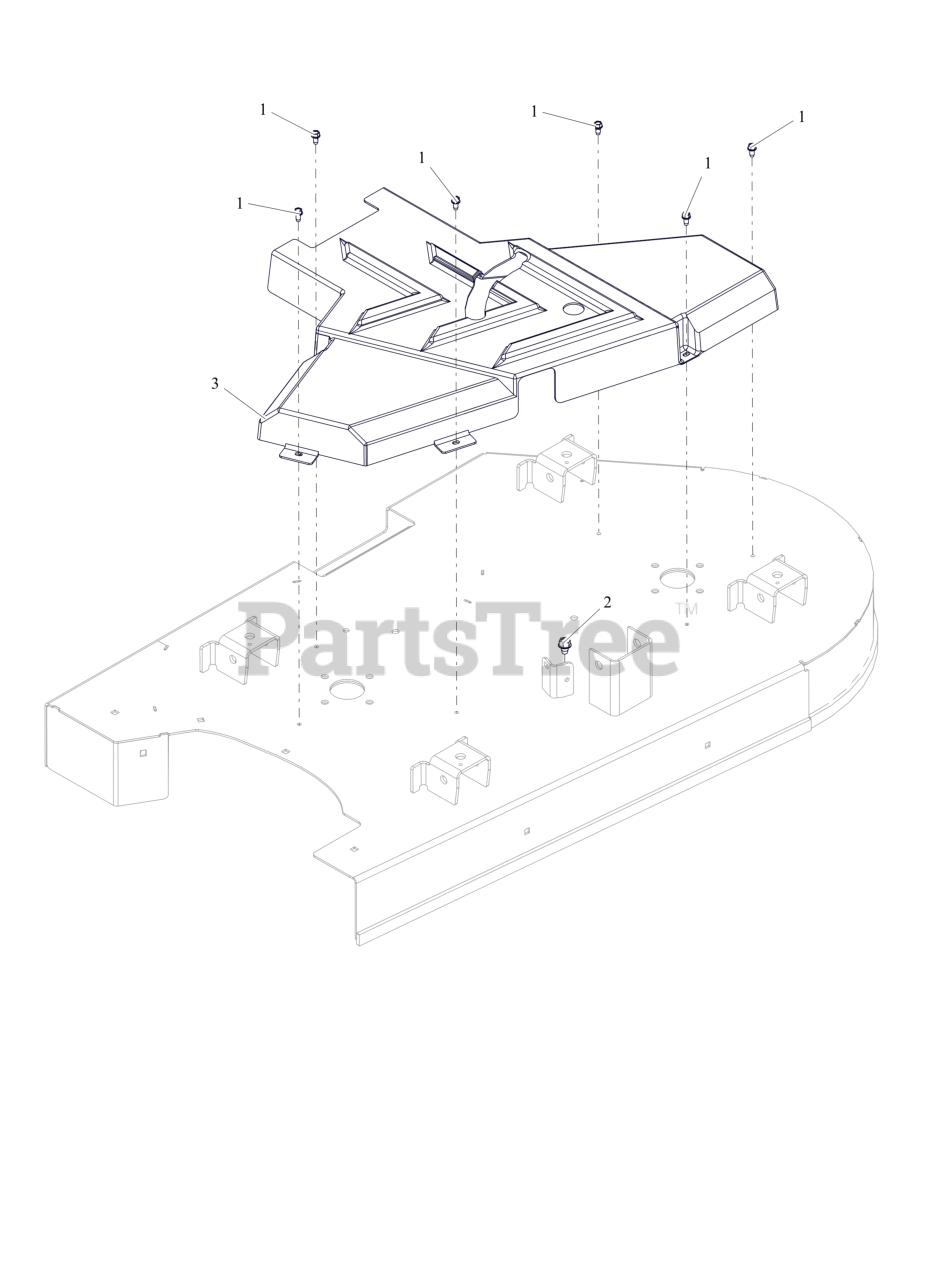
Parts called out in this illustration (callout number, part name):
1	SCR-TAP .25-20X.50 HWH ZCC
2	SCR,TAP .375-16X.50 HWH TR ZCC
3	GUARD, CENTER EDGE 42 DECK
